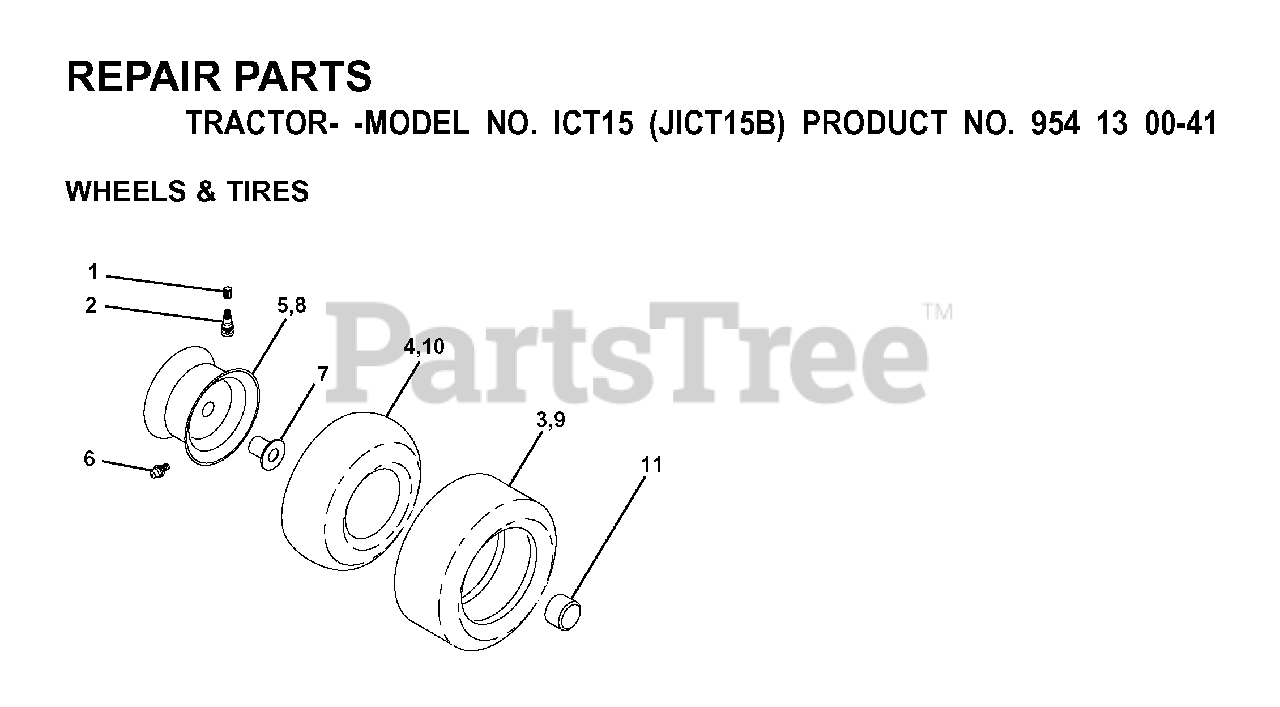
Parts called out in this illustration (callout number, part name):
1	VALVE CAP
2	VALVE STEM LT
3	TIRE HEAVY DUTY
4	TUBE.5.3/4.5/6
5	RIM ASM 6" FRONT SILVER
6	FITTING LT
7	BEARING T
8	RIM ASM 8" REAR SILVER
9	TIRE
10	TUBE
11	CAP-HUB FRONT LT
